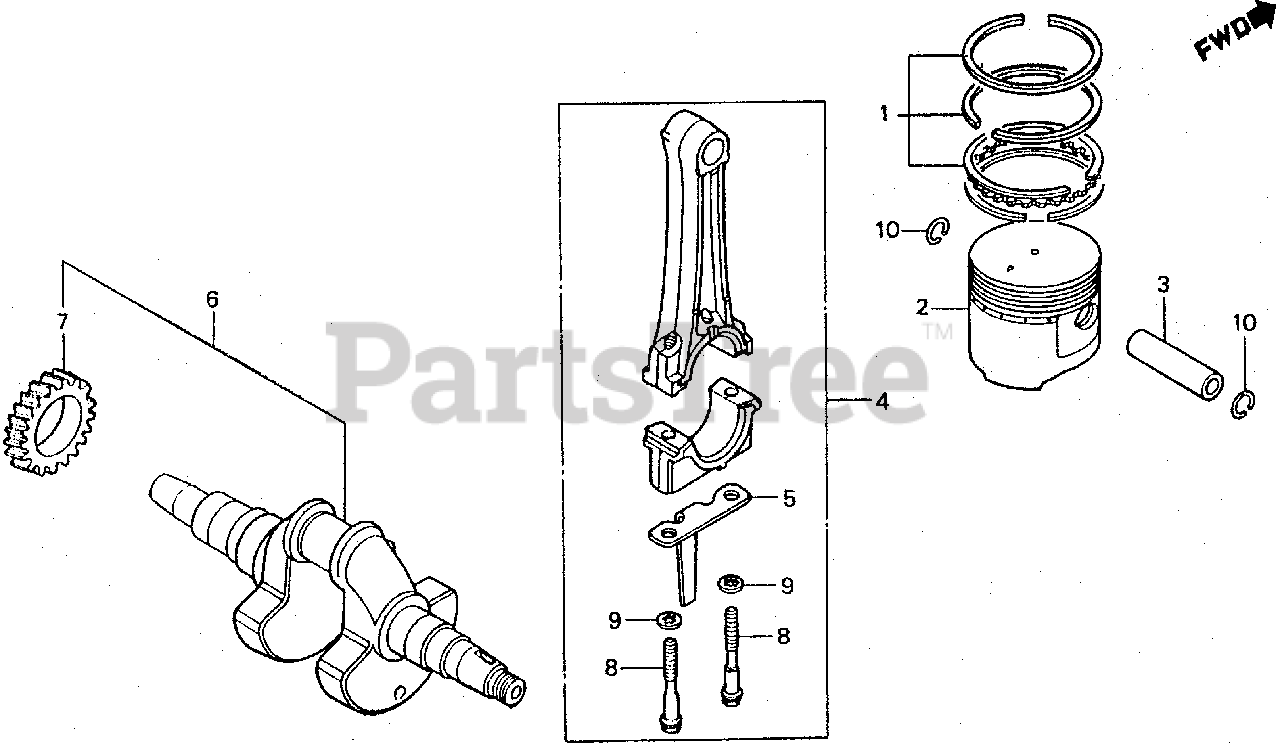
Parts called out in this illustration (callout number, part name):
1	RING SET, PISTON (STD)
1	RING SET, PISTON (OS 0.25)
1	RING SET, PISTON (OS 0.50)
1	RING SET, PISTON (0.75)
2	PISTON (STD)
2	PISTON (OS 0.25)
2	PISTON (OS 0.50)
2	PISTON (0.75)
3	PIN, PISTON
4	ROD ASSY., CONNECTING
5	DIPPER, CONNECTING ROD
6	CRANKSHAFT
7	GEAR, TIMING
8	BOLT, CONNECTING ROD (7MM)
9	WASHER, LOCK (7MM)
10	CLIP, PISTON PIN (15MM)
